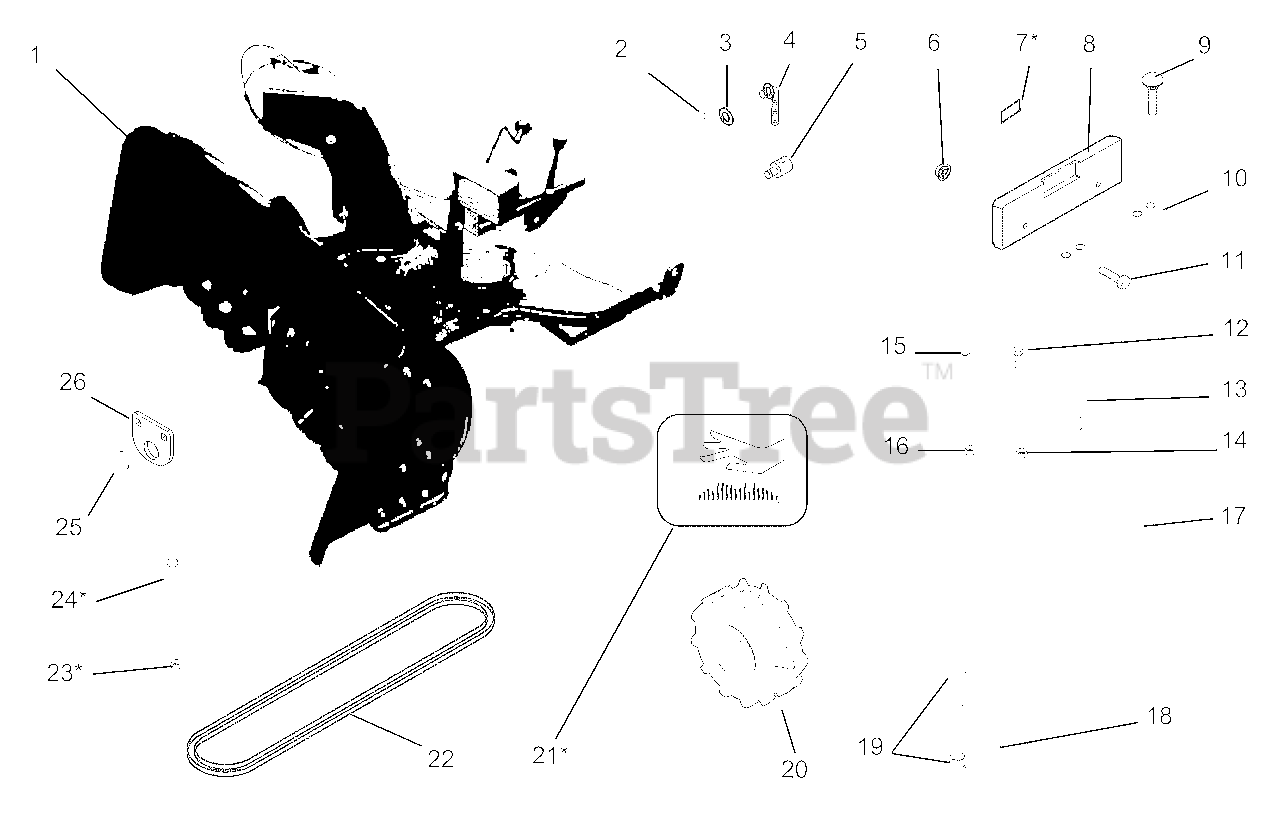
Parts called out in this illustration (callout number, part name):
1	Snow Thrower
2	PIN, HAIR, EXT - #16 YWZC
3	WSHR-FL-STL .531X1.250X.10 YWZ
4	LINK, LIFT
5	TRUNNION-.50
6	@NUT-LK-TOP-FLG .38-16 YWZC
7	REFLECTOR,TAIL(AGRI-FAB)
8	WEIGHT, CAST IRON
9	@BLT-RDHDSQNK .38-16X2.50 G5YZ
10	BRKT,ANGLE
11	@BLT-HEX .38-16X4.50 GR5 YWZC
12	@BLT-HEX .25-20X.75 GR5 YWZC
13	LATCH,COLD START
14	@NUT-LK-TOP-FLG .25-20 YWZC
15	@BLT-RDHDSQNK .38-16X2.00 G2YZ
16	@NUT-LK-CTR-JAM .375-16 YWZC
17	HANDLE,COLD START
18	WMT, IDLER ARM
19	BSHG-FLG 0.75X0.875X.625X1.125
20	ASSY,WHEEL & TIRE 18X6.5 S-HOG
21	DECAL, HOT SURFACE
22	V-BELT, 4L-RAW EDGE
23	@NUT-LK-CTR .31-18 YWZC
24	5/16" 1-12" Shear Bolt
25	BSHG-FLG 1.000X1.12X.62X1.50BR
26	BRACKET,REAR PIVOT
